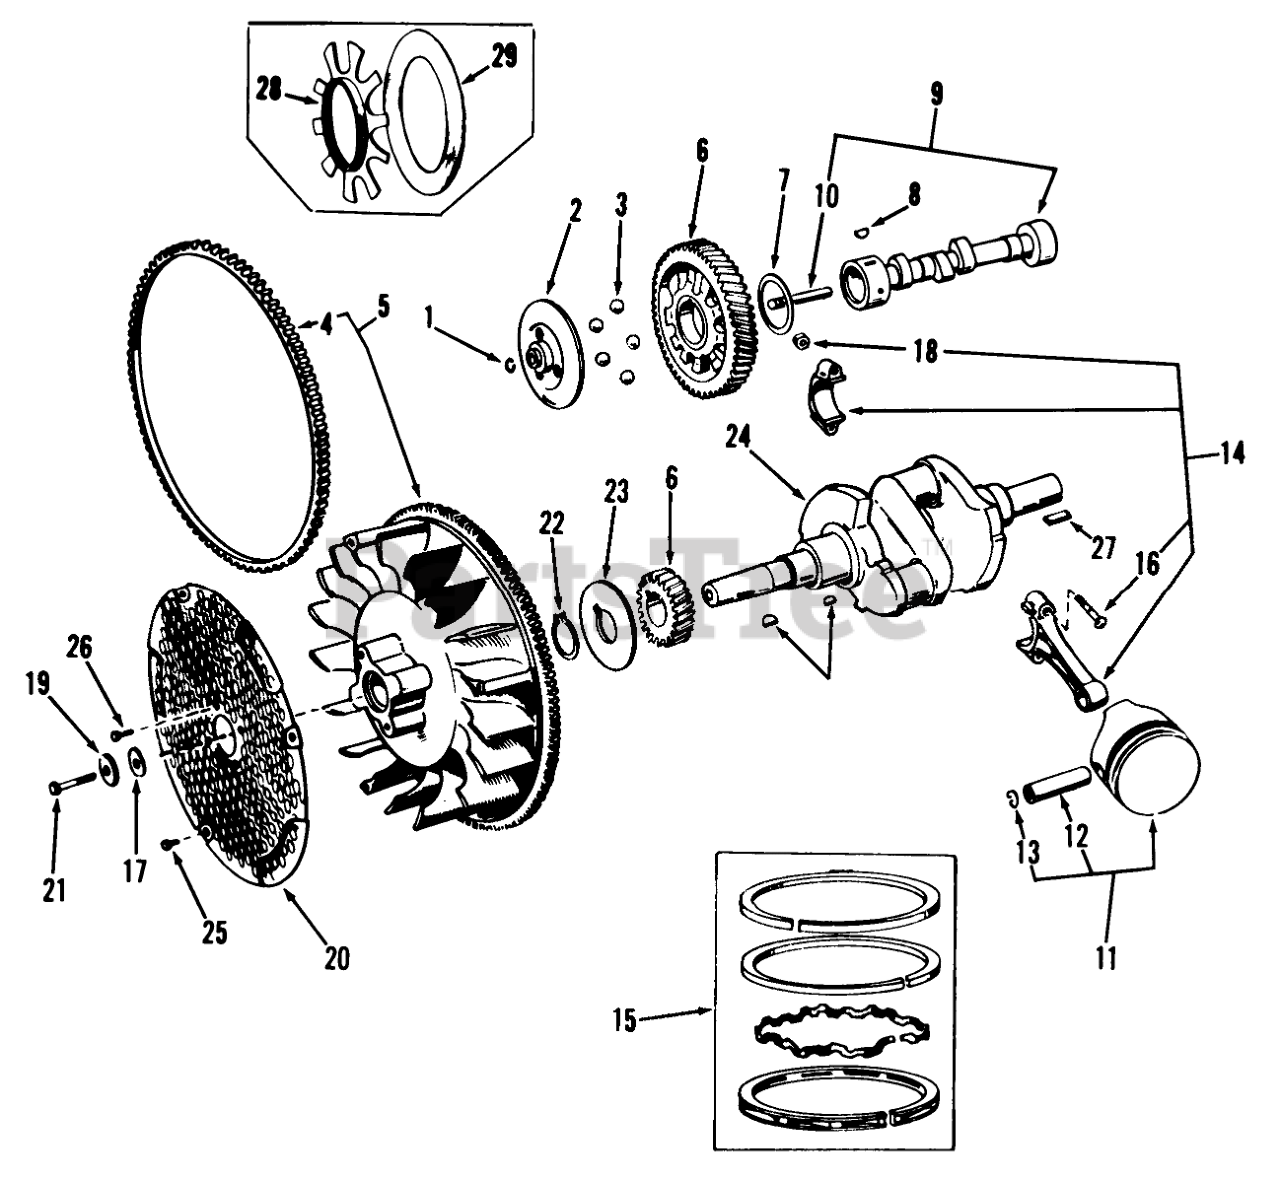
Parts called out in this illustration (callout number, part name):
1	Ring-Camshaft Center Pin
2	Governor Cup
3	Governor Fly Ball
4	Ring Gear
5	Flywheel W/Ring Gear & Magnet Ring
6	Camshaft Gear
6	Crankshaft Gear
7	Camshaft Thrust Washer
8	Key, Flywheel
8	Key, Cam & Crankshaft Gear
9	Camshaft-Includes Center Pin
10	Camshaft Center Pin
11	.005" Oversize
11	Standard
11	.040" Oversize
11	.030" Oversize
11	.020" Oversize
11	.010" Oversize
12	Wrist Pin
14	.010" Undersize
14	Standard
14	.030" Undersize
14	.020" Undersize
15	SET-PISTON RING +005
15	SET-PISTON RING STD
15	.040" Oversize
15	.030" Oversize
15	.020" Oversize
15	SET-PISTON RING +010
16	Connecting Rod Bolt (Special)
17	Washer 7/16
18	Lock Nut-Connecting Rod
19	Lockwasher 7/16 Flywheel
20	Flywheel Guard
21	Hex Bolt
22	Retaining Ring
23	Washer-Crankshaft Gear
24	CRANKSHAFT
25	Bolt 1/4-20 X 1/2 Whizlock
26	Locking Screw 5/16-18 X 1/2
27	Key
28	Spacer,Governor Flyball
29	Plate,Governor Flyball
